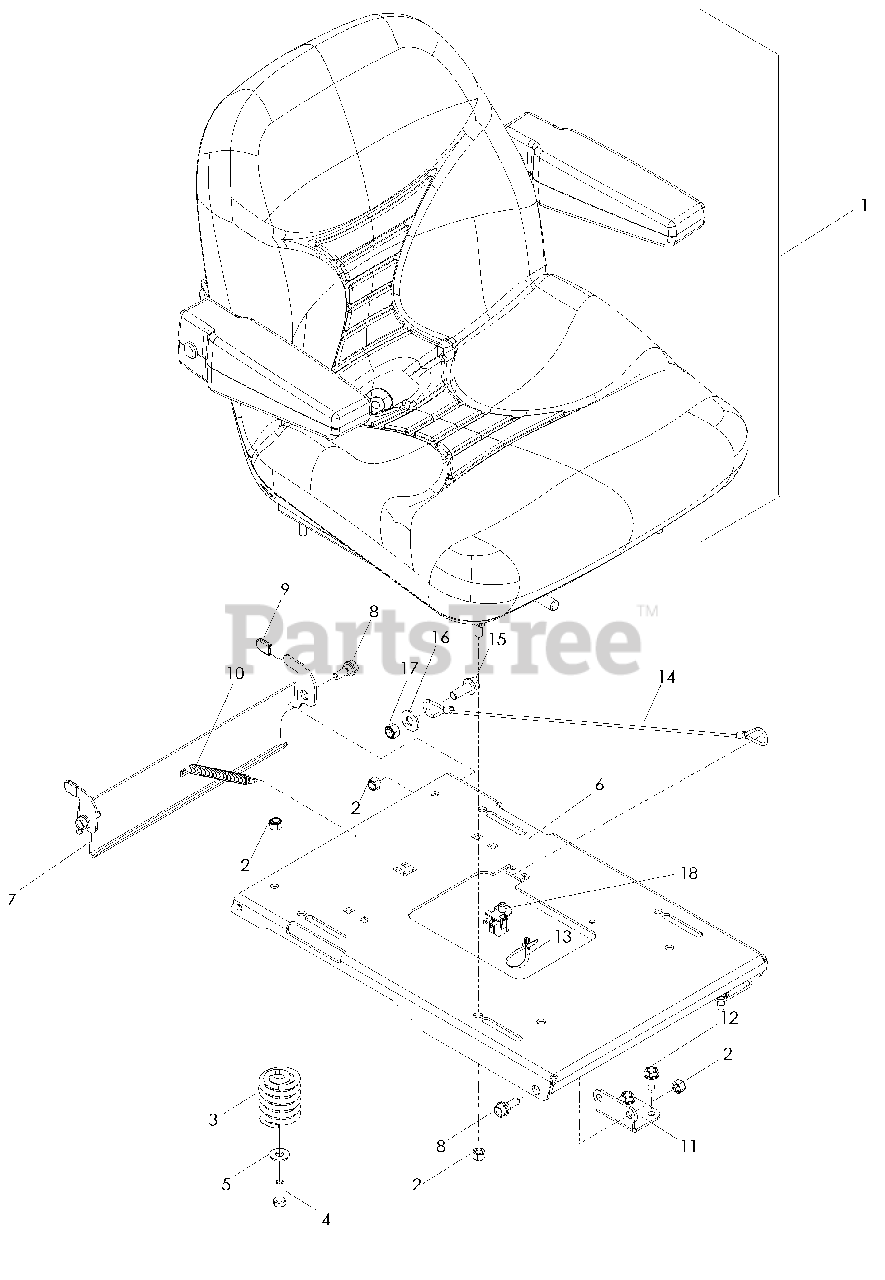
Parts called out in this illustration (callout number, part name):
1	Seat
2	Nut 5/16-18 Hex Nyloc
3	Spring, Seat
4	Hcs 5/16-18 x 1
5	Washer 5/16 Std Flt
7	Latch, Seat
8	Sb 5/16-18 Hex Hd
9	Grip, Vinyl
11	Pivot, Seat Pan
12	Bolt 5/16-18 x 3/4 Trd Frm
13	Tie Wrap W/Clip
14	Lanyard, Seat
15	Hcs 3/8-16 x 1 Whizlk
16	Washer 3/8 Std Flt
17	Nut 3/8-16 Hex Nyloc
18	Switch, Seat
